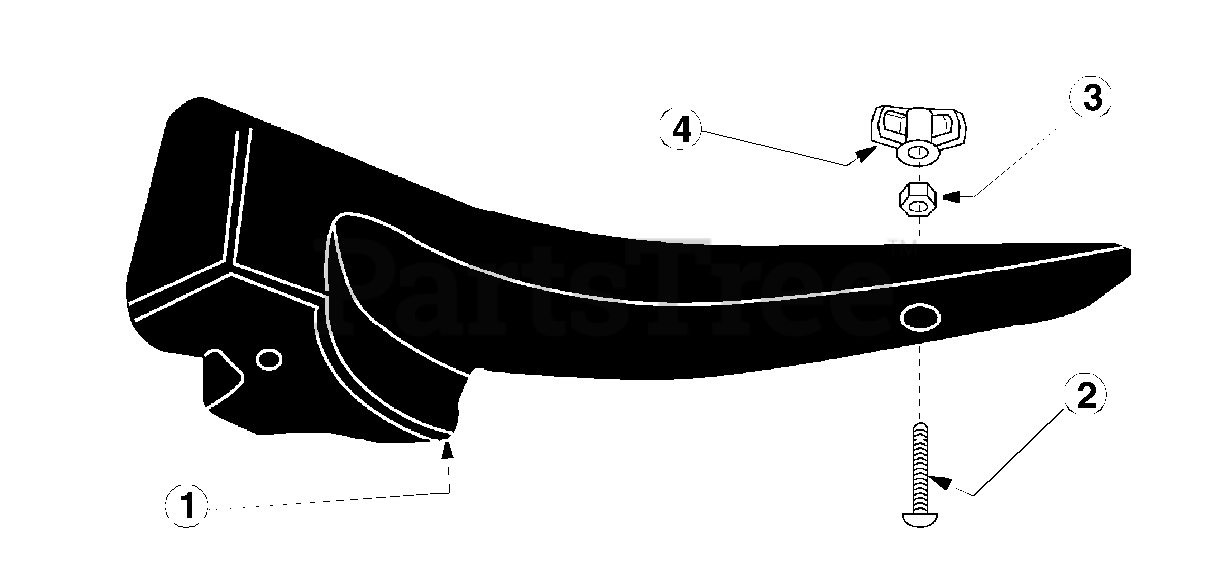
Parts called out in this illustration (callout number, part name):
1	Mulching Plug
2	16.28" 3 in 1 Blade
3	14.88" 3 in 1 Blade
4	Machine Screw (1/4")
